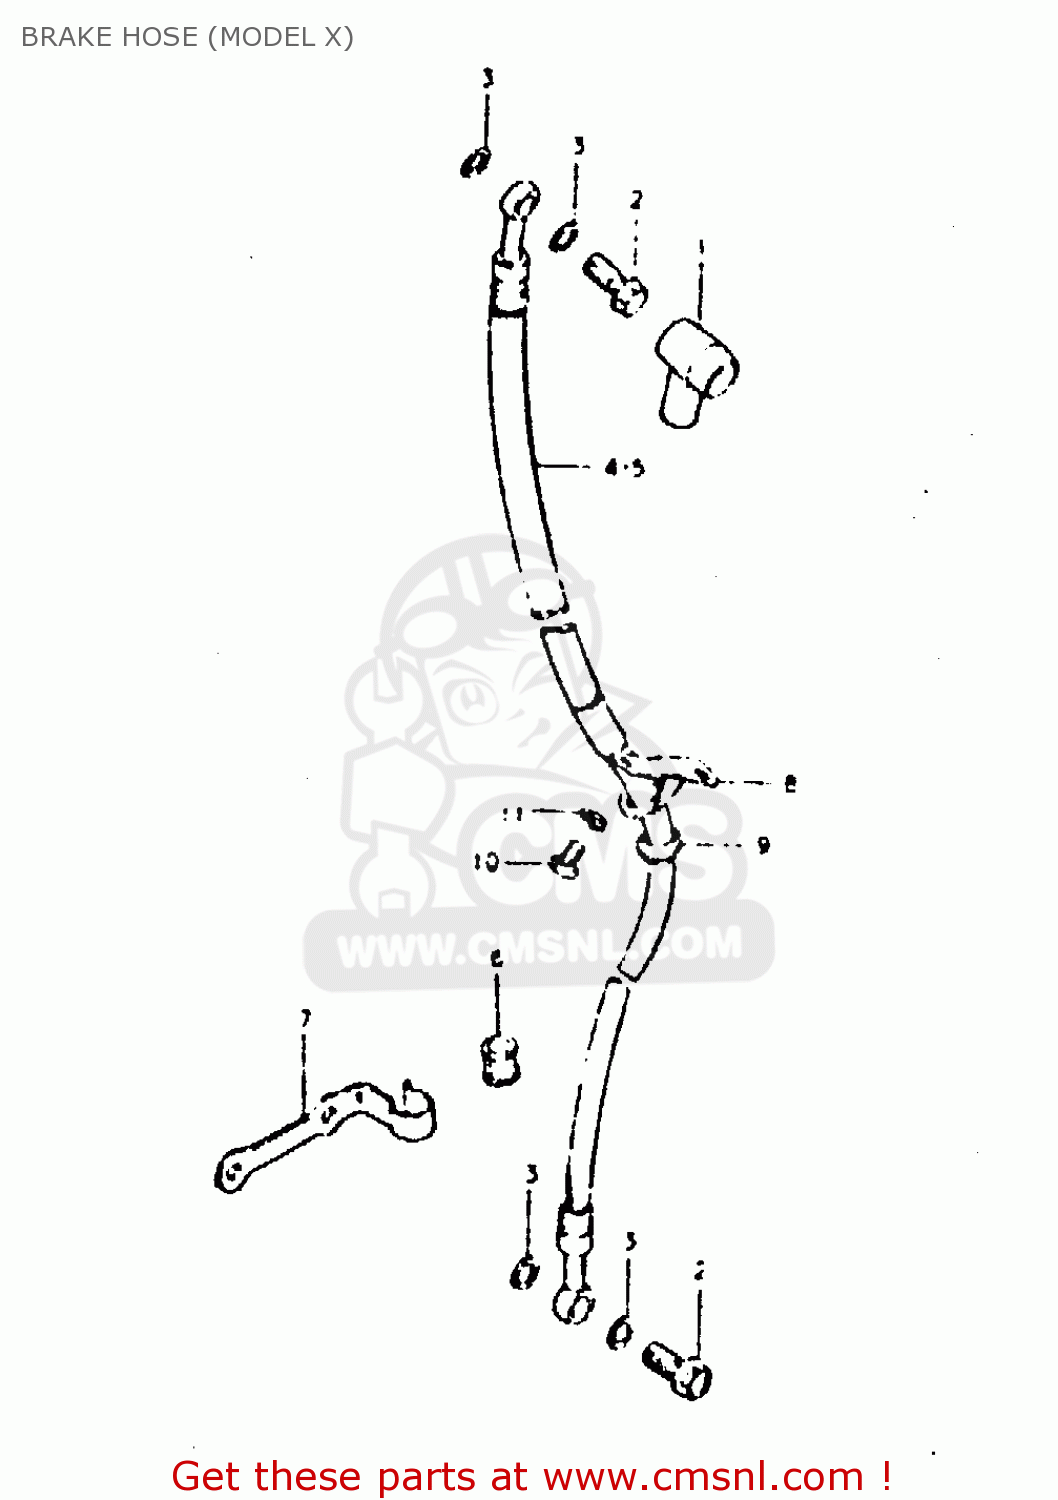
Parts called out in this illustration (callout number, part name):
1	BOOT,MASTER CYLINDER
2	BOLT,UNION
3	WASHER
4	HOSE, BRAKE (NEUTRAL)
5	HOSE, BRAKE (FLAT)
6	BUSH,BRAKE HOSE GUIDE,NO.2
7	CLAMP,BRAKE HOSE
8	GUIDE,BRAKE HOSE
9	GROMMET,BRAKE HOSE GUIDE
10	BOLT
11	LOCK WASHER
